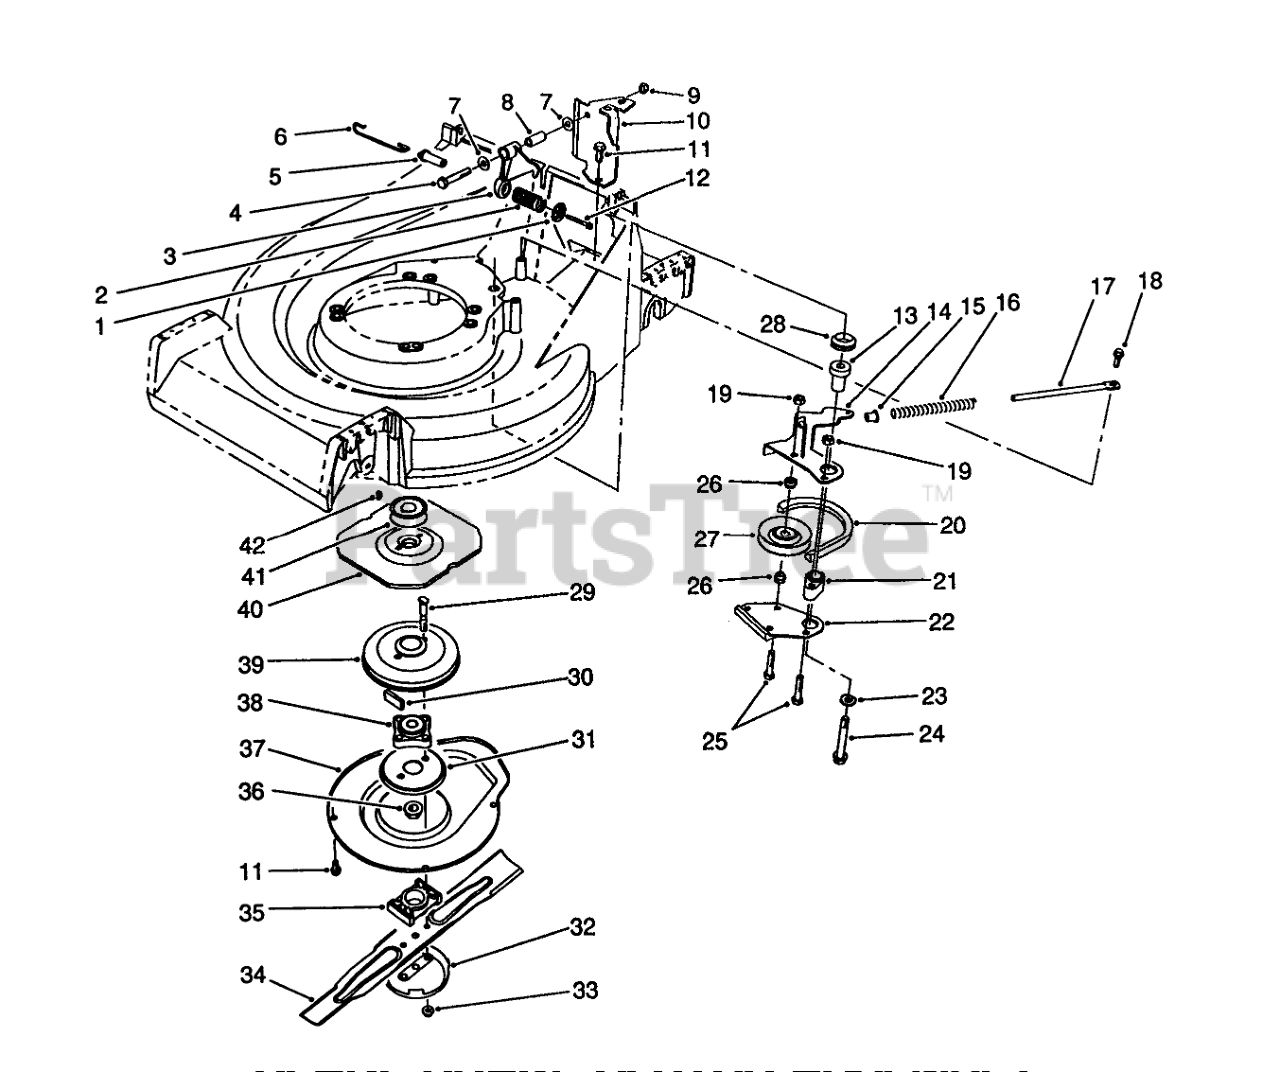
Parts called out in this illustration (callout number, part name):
1	RETAINER-SPRING
2	COMPRESSION SPRING
3	CRANK
4	SCREW-HH
5	SPRING PIN
6	CONTROL LINK
7	WASHER-PLAIN
8	STRAIGHT BUSHING
10	Bracket-Cable Support
11	SCREW-HWHTF
12	SCREW-HWHTF
13	BBC PM BUSHING
14	Lever
15	SPACER
16	COMPRESSION SPRING
17	SPRING ROD
18	SCREW-SHOULDER
19	NUT-LOCK, NI
20	V-BELT
21	BRAKE PLATE HUB
22	BRAKE SHOE
23	WASHER-PLAIN
24	3/8-16 X 2-3/4 CAPSCR
25	SCREW-HH
26	IDLER PULLEY HUB
27	PULLEY-IDLER
28	V-RING SEAL
29	BOLT-BLADE
30	DAMPENER-VIBRATION
31	Screen-BBC
32	Anti Scalp Cup
33	NUT-LOCK
34	Key
35	SPACER-BLADE
36	NUT-LOCK, NI
37	Cover
38	HUB ASM
39	BRAKE DRUM
40	FLYWHEEL - BBC
41	PULLEY
42	KEY-WOODRUFF
